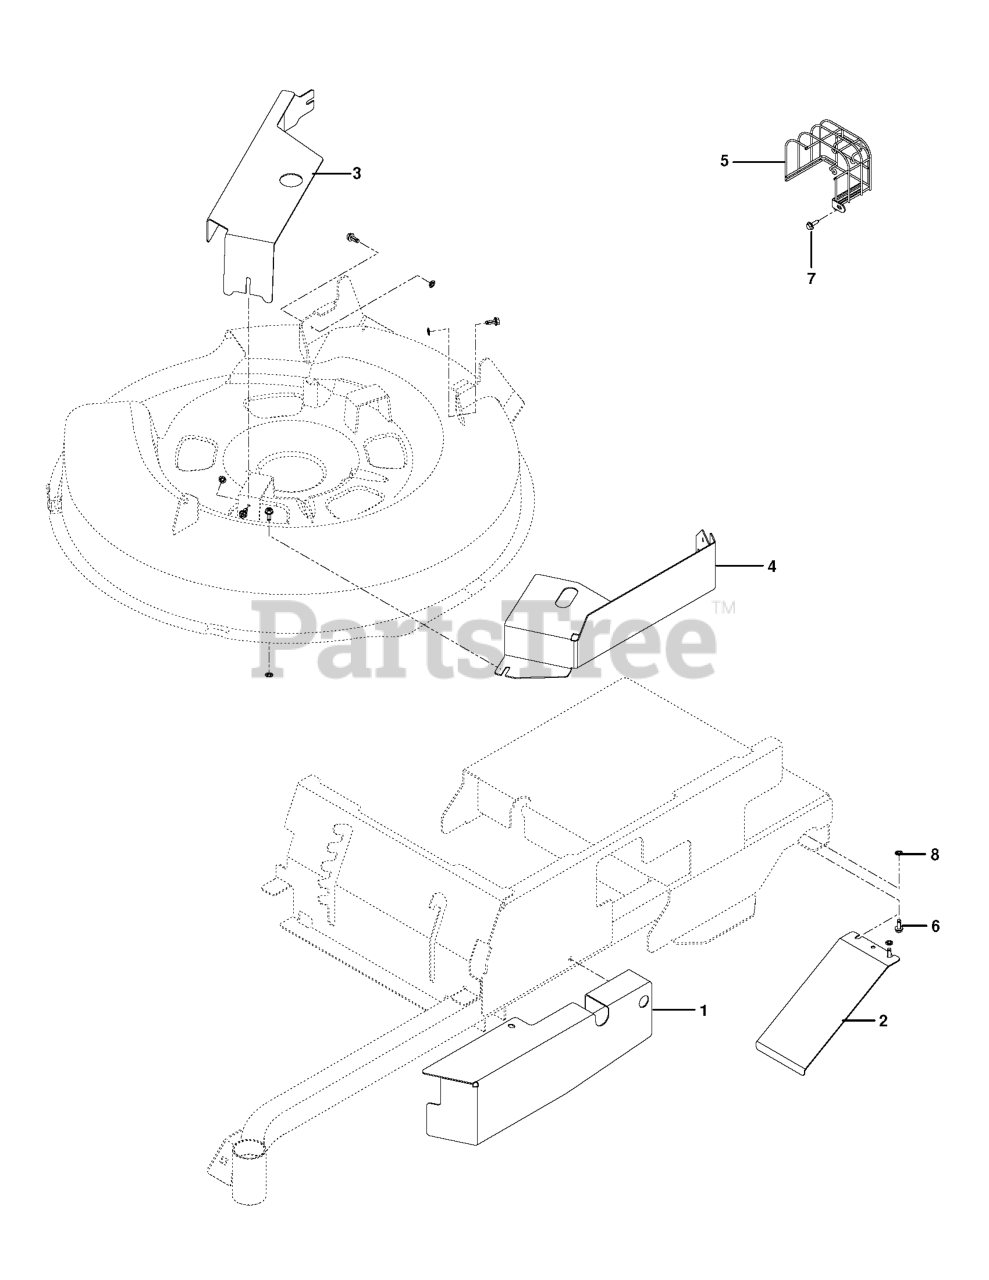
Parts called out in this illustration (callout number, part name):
3	GUARD, SPINDLE BLK
4	GUARD, CLUTCH BLK
6	PALNUT 1/4
8	PALNUT 1/4
